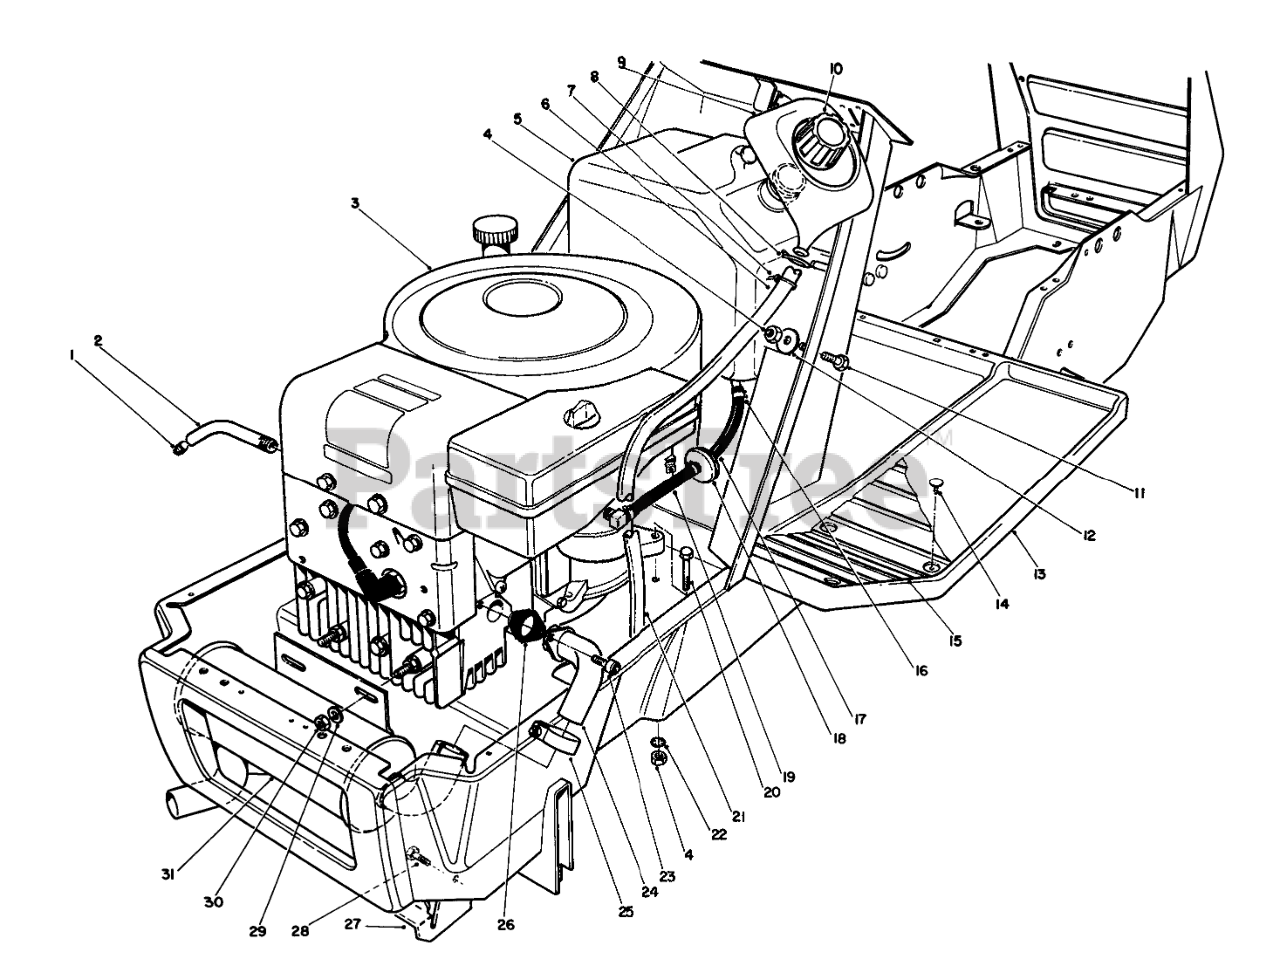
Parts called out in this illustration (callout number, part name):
1	PLUG-PIPE, SQH
2	OIL DRAIN TUBE
3	Engine
4	NUT-LOCK, NI
5	Tank-Fuel (Incl. Ref. #9 & 10)
6	HOSE -RETURN
7	TIE-CABLE
8	HOSE CLAMP
9	Funnel-Overflow
10	GAS CAP ASM
11	SCREW-HH
12	WASHER
13	FRAME WA RO
14	FASTENER-PANEL
15	L/H FOOTREST TREAD
16	CLAMP-HOSE
17	Hose-Fuel
18	Filter-Fuel
19	Hose Fuel
20	SCREW-HH
21	FUNNEL HOSE
22	WASHER-LOCK, INTERNAL
23	SCREW-HSH
24	12 HP EXHAUST PIPE WA
25	MUFFLER CLAMP
26	Gasket-Exhaust
27	MUFFLER HEAT SHIELD R
28	Screw-Hex. Hd.
29	WASHER-PLAIN
30	NUT-LOCK, CONE
31	Muffler
